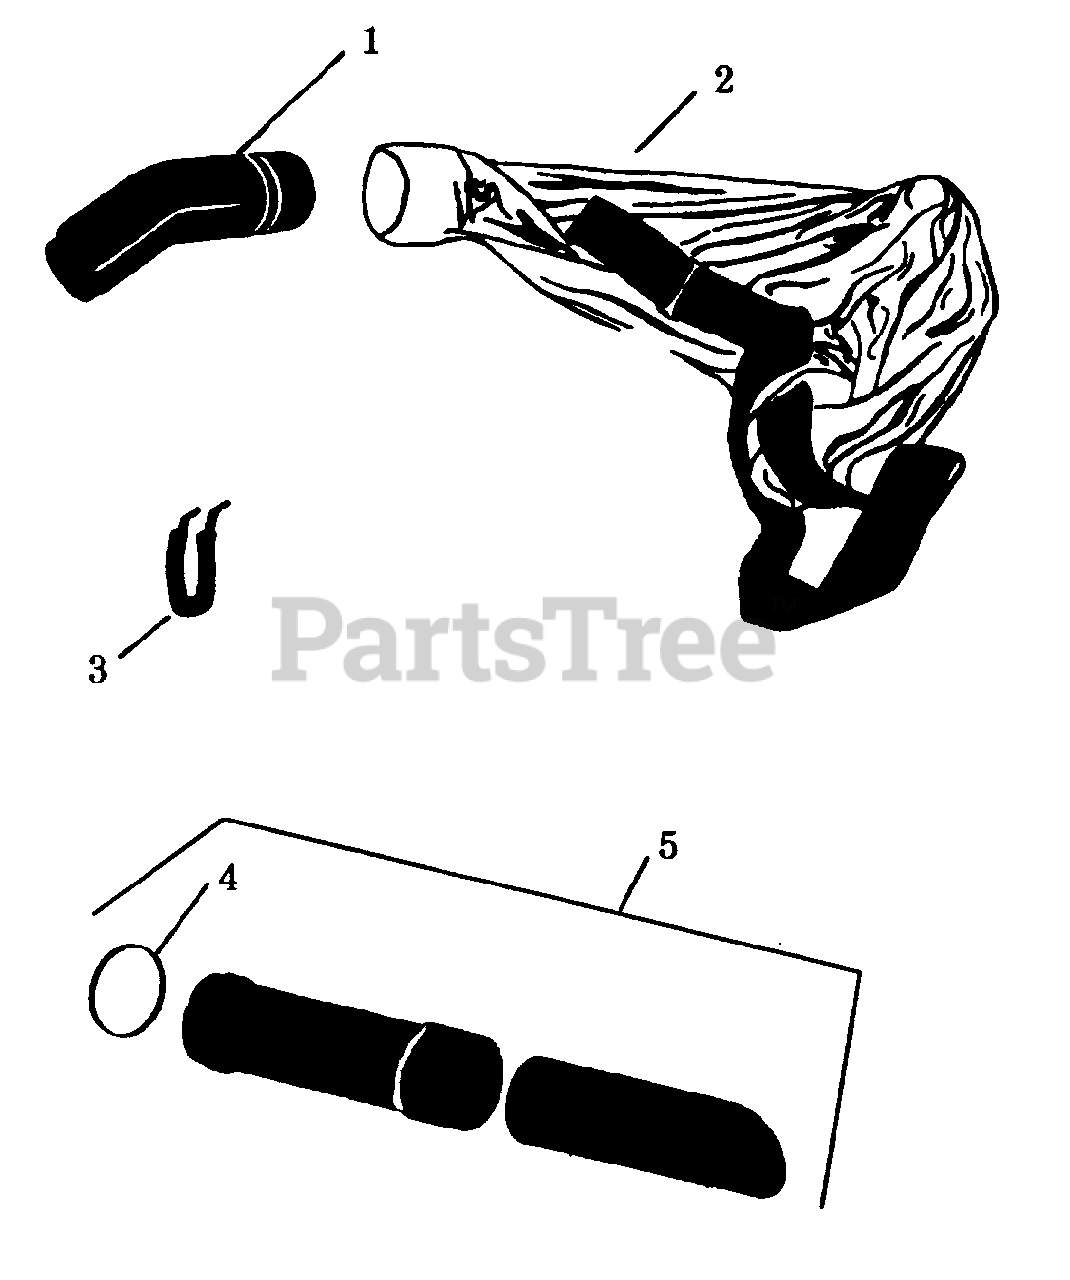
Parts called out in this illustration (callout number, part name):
2	Vacuum Bag Kit
3	Rear Handle Ass'y.
4	Spacer
5	Vacuum Tube Kit
